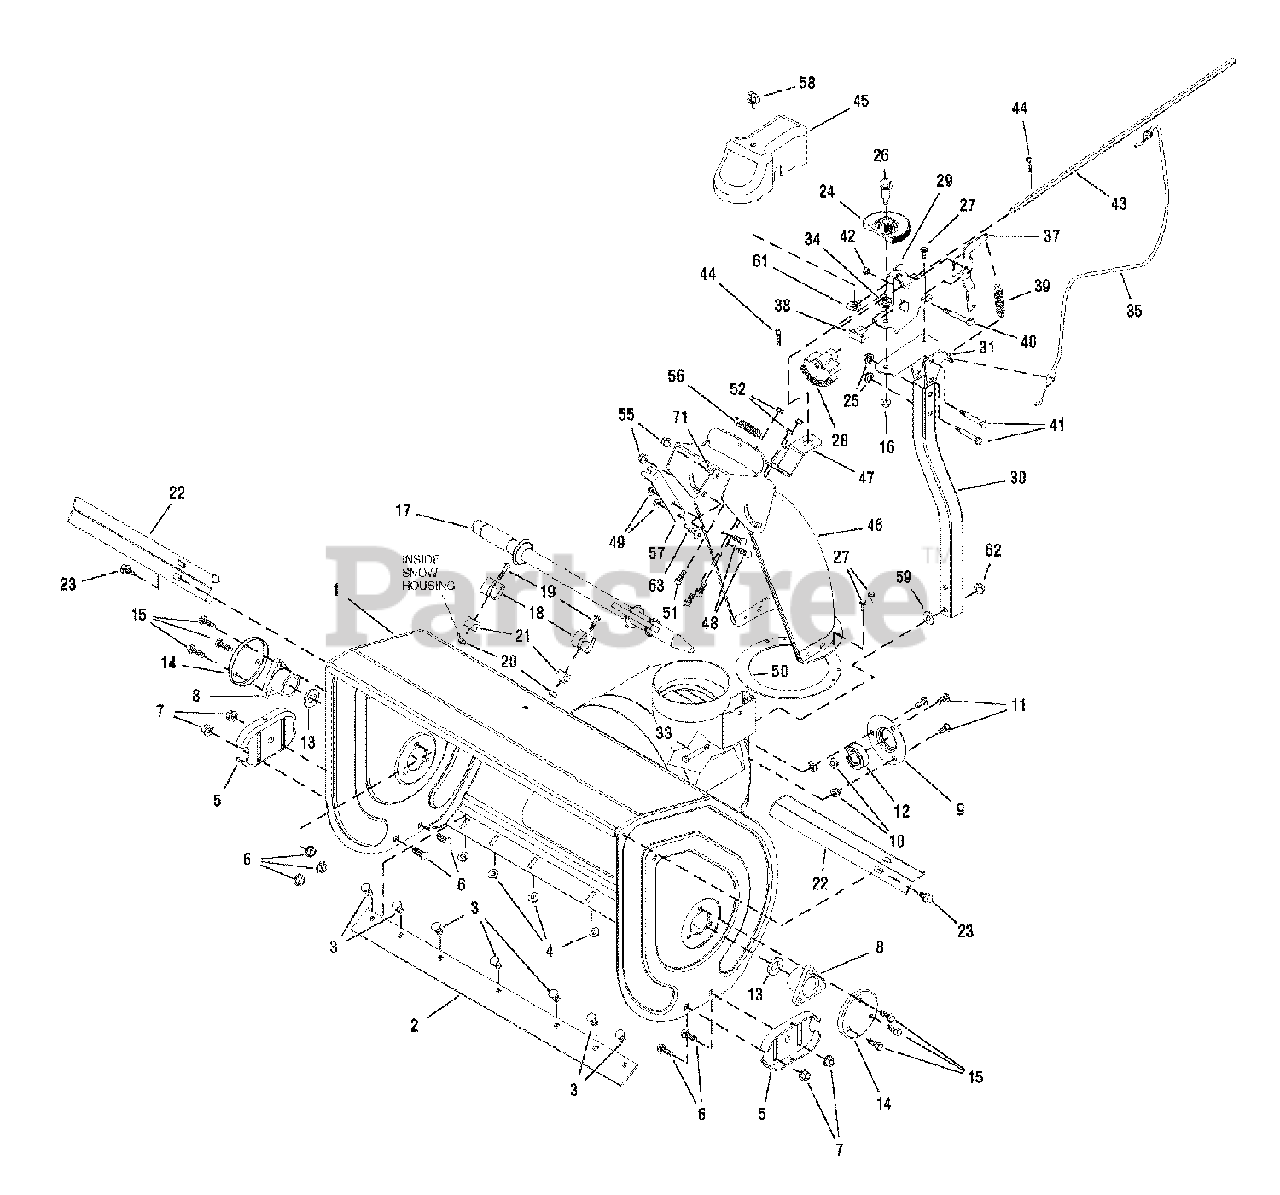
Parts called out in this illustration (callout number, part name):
1	HOUSING ASSEMBLY, 26"
1	HOUSING ASSEMBLY, 28"
1	HOUSING ASSEMBLY, 30"
1	HOUSING ASSEMBLY, 32"
2	BLADE, Scraper 26"
2	BLADE, Scraper 28"
2	BLADE, Scraper 30"
2	BLADE, Scraper 32"
3	CARRIAGE BOLT, 5/16-18 x5/8 G5
4	NUT, Hex Flange Two-Way Lock, 5/16-18
5	SKID, Shoe Reversible
6	CARRIAGE BOLT, 3/8-16 x 3/4 G5
7	NUT, Hex Flange 3/8-16 ESNA
8	BEARING, Flange
9	BEARING, Retainer
10	RETAINER, Nut, 5/16-18
11	SCREW, Hex Whiz Lock Flange, 5/16-18 x 3/4
12	BEARING
13	SPACER
14	CAP, Bearing
15	CAPSCREW, Hex Head, 5/16-18 x 7/8 G5
16	NUT, Hex Flange Whiz Lock, 5/16-18
17	STICK, Cleanout w/Brush
18	CLIP, Retainer
19	CAPSCREW, Hex Washer, #10 x 1-1/4
20	NUT, Hex Lock
21	BLOCK, Universal Pivot
22	CUTTER, Drift w/Tabs
23	SCREW, Hex Washer Head Taptite 5/16-18 x 3/4
24	GEAR, 13Tooth
25	NUT, Hex Keps Conical Washer, 5/16-18
26	BOLT, Shoulder 5/16-18
27	SCREW, Hex Washer Head Taptite 1/4-20 x 1/2
28	GEAR, 34 Tooth
29	SUPPORT, Driver Gear
30	TUBE
31	BRACKET, Gear Support
32	WASHER, 3/8
33	CAPSCREW, Hex Head 3/8-16 x 2 G5
34	WASHER, Powdered Metal
35	CABLE, Chute Brake
38	ARM & PAD ASSEMBLY, Brake
39	SPRING, Extension
40	CAPSCREW, Hex Head 1/4-20 x 2-1/2 G5
41	CAPSCREW, Hex Head 5/16-18 x 2 G5
42	NUT, Hex Centerlock 1/4-20
43	ROD, Hex
44	PIN, Quick
45	COVER, Chute
46	CHUTE & DEFLECTOR ASSEMBLY
47	BRACKET, Chute Support
48	CARRIAGE BOLT, 1/4-20 x 5/8 G5
49	NUT, Hex Flange Whiz Lock 1/4-20
50	RING, Chute Base
51	SCREW, Truss Head Torx 1/4-20 x 3/4
52	NUT, Hex Lock ESNA Light 1/4-20
55	NUT, Hex Flange 5/16-18 ESNA
56	SPRING, Extension
57	BRACKET, Cable
58	KNOB & SCREW ASSEMBLY
59	LOCKWASHER, Spring 3/8
61	NUT, Retainer Speed #10-24 w/Extrusion
62	NUT, Hex Keps, 3/8-16 Conical Washer
63	SCREW, Truss Head Torx 5/16-18 x 7/8
71	CAPSCREW, Hex Head 5/16-18 x 3/4 G5
0800	BOLT, 1/2 x 3
